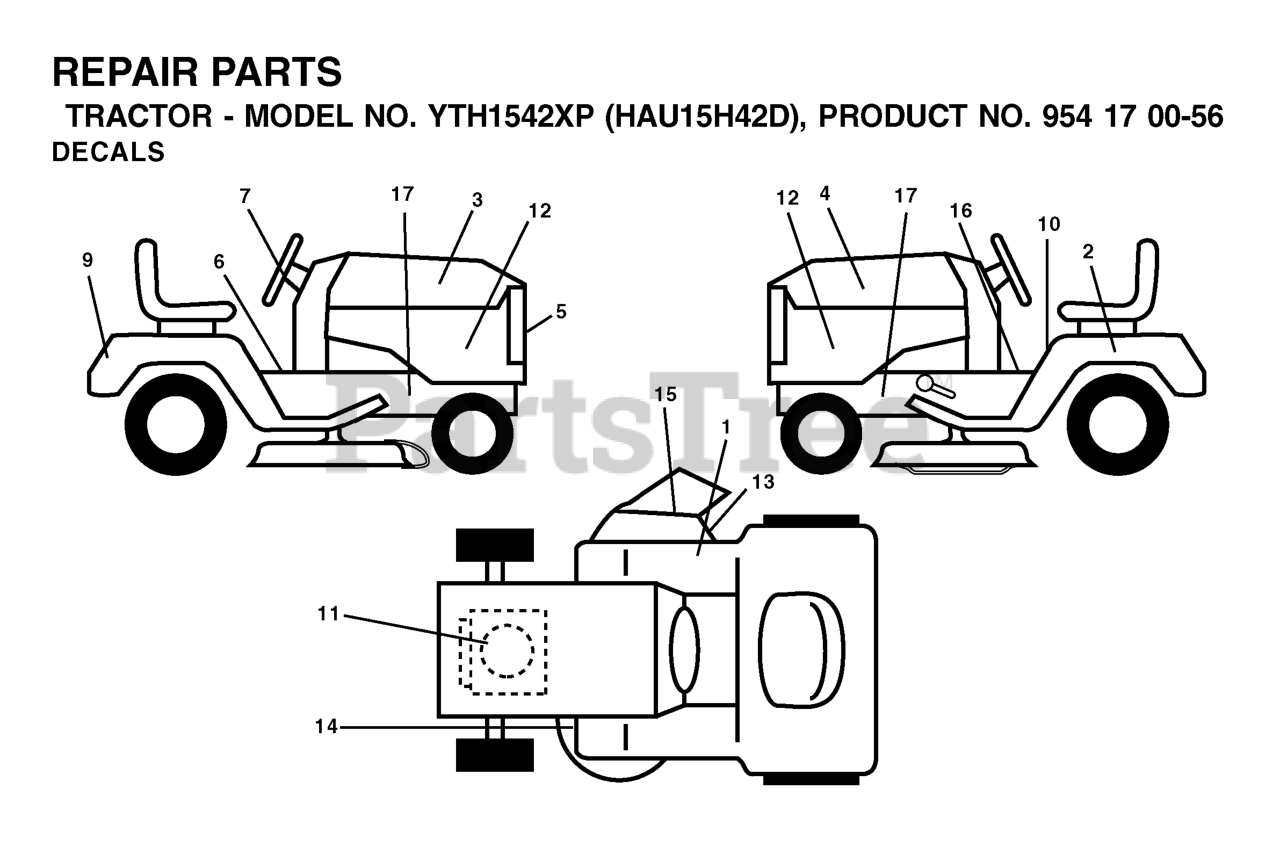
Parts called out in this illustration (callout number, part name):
1	DECAL
2	DECAL BTRY SYMBOLS
3	DECAL HOOD RH
4	DECAL HOOD(L)YTH1542XP
5	DECAL.GRILLE.HUSQ
6	DECAL PARK BRAKE
7	DECAL.WHEEL.STEERING.HUSQ.PERM
9	DECAL, FENDER
10	DECAL READ OWNER'S MAN SYMS
12	DECAL HOOD
13	DECAL.INTERNATIONL.CUTFINGER
14	DECAL V BELT SCHEMATIC
15	DECAL DECK "B" 42"
16	DECAL
